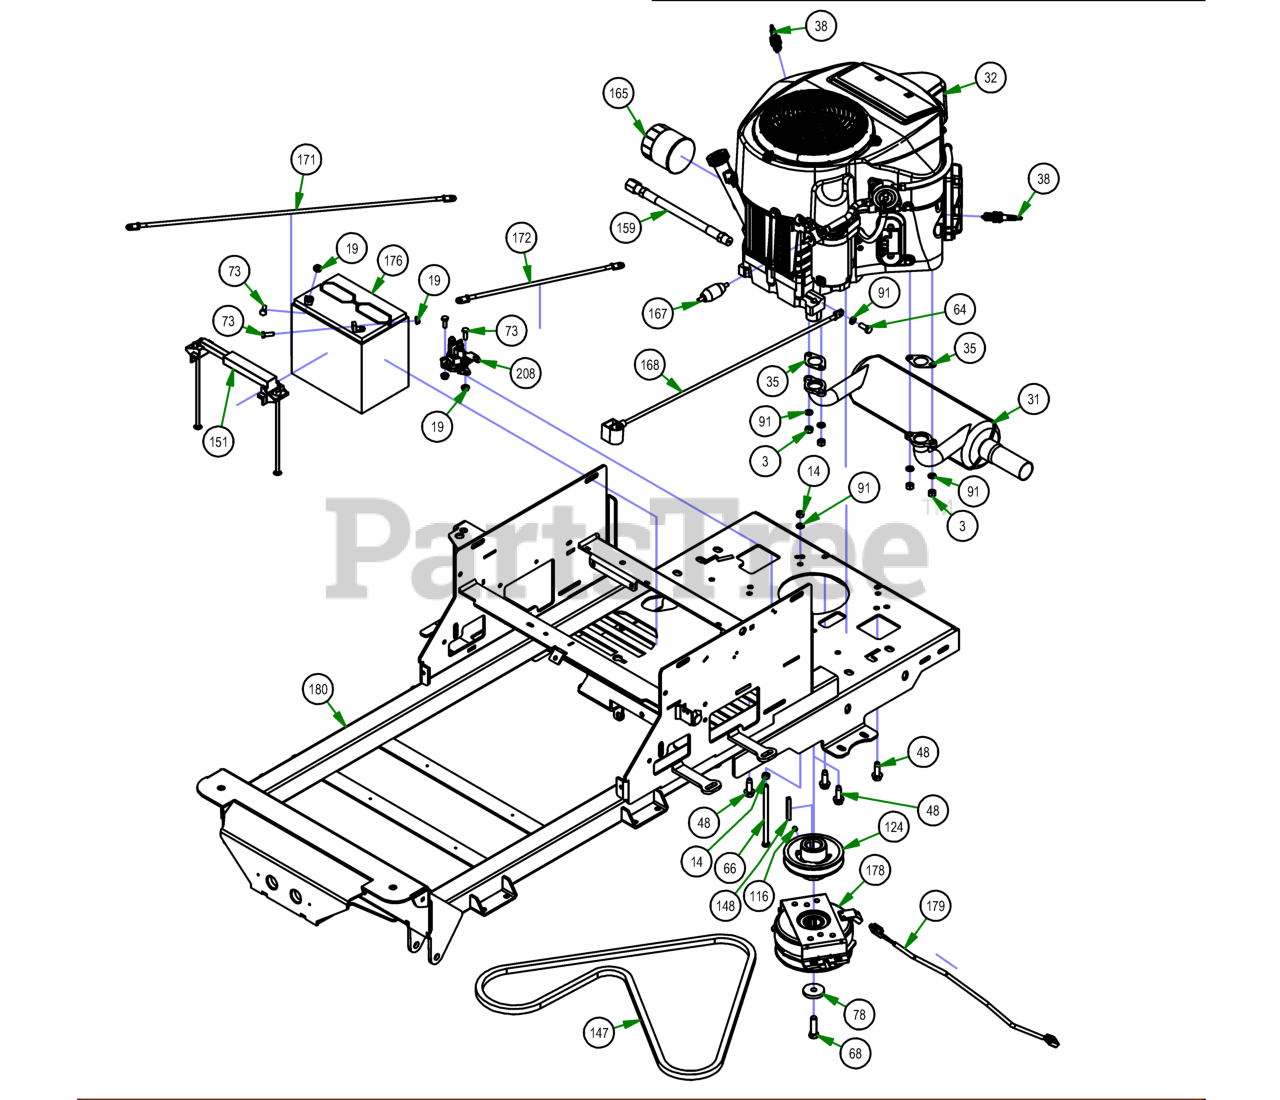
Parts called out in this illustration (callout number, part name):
3	M8-1.25 DIN 934 HEX NUT (CL.8) ZINC
14	5/16-18 HEX NUT ZINC
19	1/4-20 HEX SERRATED FLANGE NUT HARD/ZINC
31	Kawasaki Muffler 1251
32	FR 730V-S16 Kawasaki Engine 1.125" shaft-ZT
35	Exhaust Gasket
38	Spark Plug - Kawasaki
48	3/8-16 X 1-1/8 HEX WASHER UNSLOT SERRATED (TRI-LOB) TRS ZINC YELLOW
64	M8-1.25 X 20MM DIN 933 HEX TAP BOLT (CL 8.8) ZINC
66	5/16-18 X 5-1/2 HEX CAP SCREW (GR.5) ZINC
68	7/16-20 X 1-1/2 HEX CAP SCREW (GR.8) ZINC YELLOW
73	1/4-20 X 3/4 HEX CAP SCREW (GR.5) ZINC
78	CLUTCH WASHER
91	5/16 SPLIT LOCKWASHER ZINC
116	5/16-24 X 1/4 SOCKET SET SCREW (CUP PT) PLAIN
124	4 3/4 Motor Pulley
148	1/4 X 2 SQ MACHINERY KEY 1018 STL PLAIN
151	Hold Down Assembly
159	Oil drain Hose
165	22-26 Kaw Oil Filter FR Engine
167	Universal Inline Fuel Filter
168	24 inch Black Cable – MZ/ZT
171	24" Red Battery Cable
172	12 in red battery cable
176	SP-35 Battery
179	Clutch Pigtail
180	2021 ZT Frame - Painted
